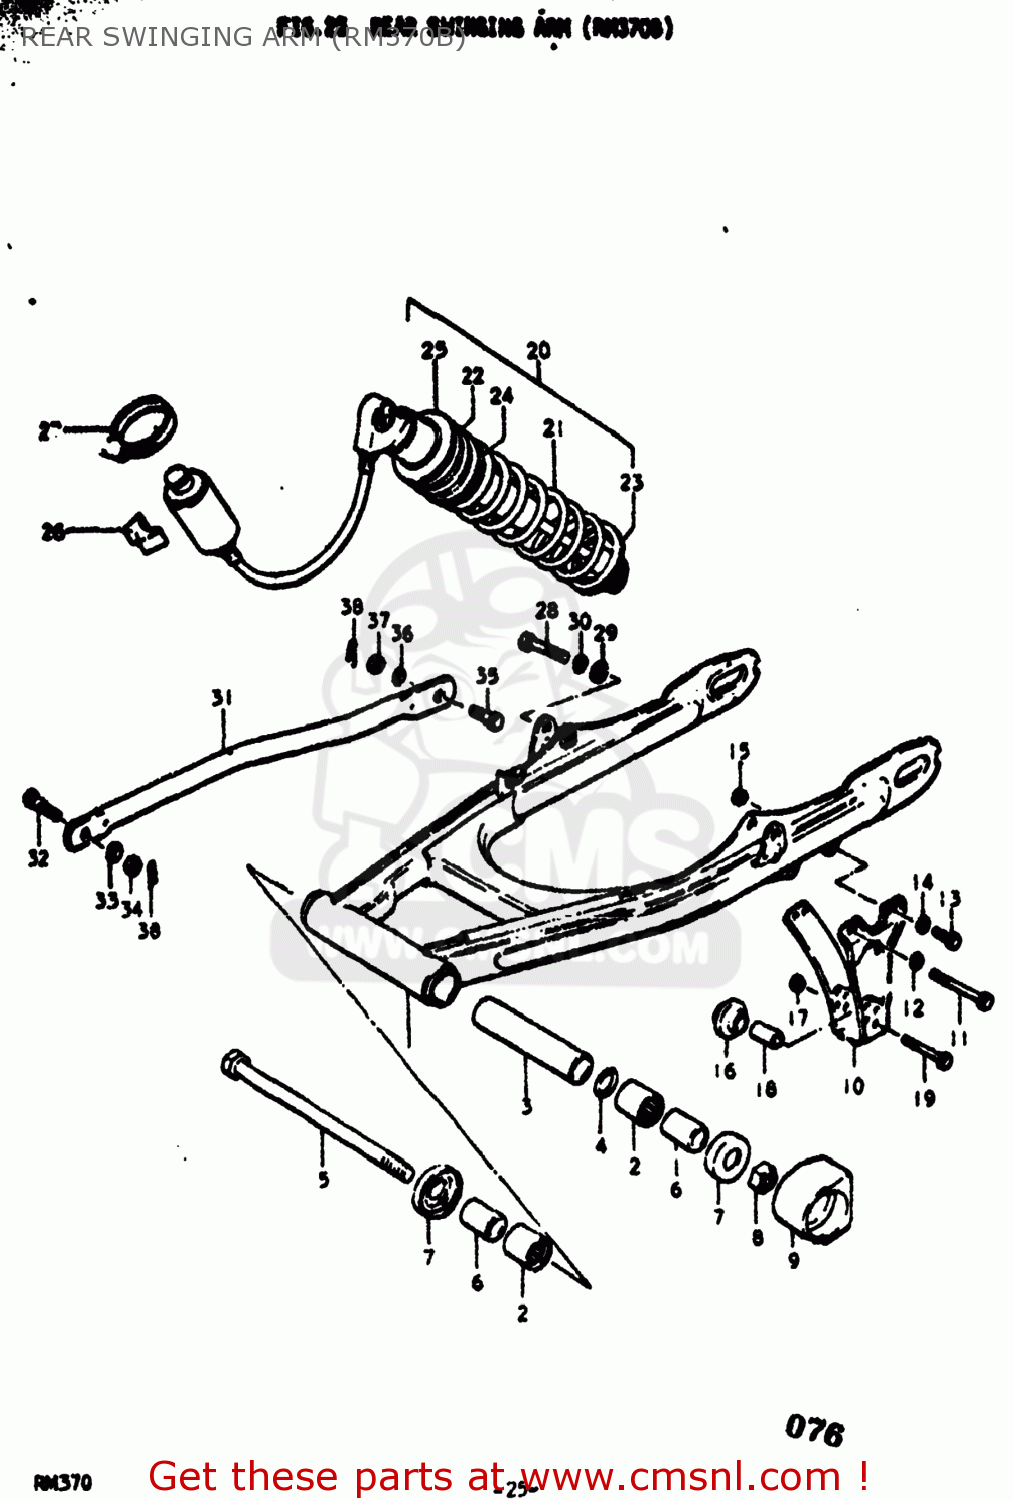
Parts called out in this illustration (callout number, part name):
1	SWING ARM ASSEMBLY,REAR
2	BEARING(20X28X25)
3	SPACER,REAR SWING ARM
4	O RING(D:1.9,ID:18.8)
5	SHAFT,REAR SWING ARM
6	SPACER(14X20X30)
7	THRUST BEARING IKO
8	NUT
9	BUFFER,CHAIN TOUCH DEFLECTOR
10	GUIDE,CHAIN
11	BOLT
12	LOCK WASHER
13	BOLT
14	LOCK WASHER
15	NUT
16	RUBBER,CHAIN GUARD
17	NUT (6MM)
18	SPACER(6.5X10.5X22.5)
19	BOLT
20	ABSORBER ASSEMBLY,REAR SHOCK
21	SPRING
22	SPRING
24	SPRING
25	GUIDE,SPRING
26	CUSHION,RR SHOCK ABSORBER
27	CLAMP
28	BOLT 10X40
29	WASHER
30	LOCK WASHER
31	TORQUE LINK,REAR
32	BOLT(8X22.5)
33	LOCK WASHER
34	NUT
35	BOLT(10X31)
36	LOCK WASHER
37	NUT
38	CLIP
